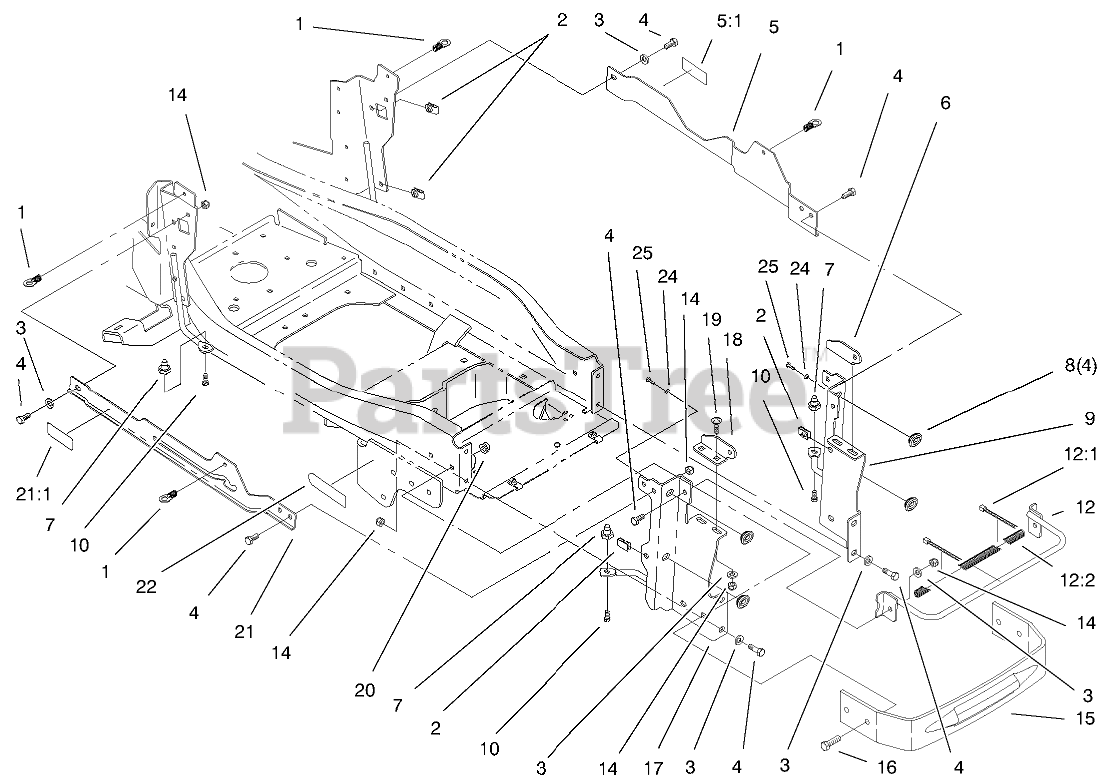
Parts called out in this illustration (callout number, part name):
1	LATCH ASM
3	WASHER-PLAIN
4	SCREW-HH
5	Support ASM (Only On: 73470, 73540)
5	Support ASM (Only On: 73541)
5:1	Decal-Warning (Only On: 73470, 73540)
5:1	Decal-Warning (Only On: 73541)
6	BRKT-LOWER HINGE LH (BLACK)
7	MOUNT-SIDEPANEL
8	GROMMET
9	SUPPORT-HOOD, LH
10	SCREW-PLASTITE
12	ASSEMBLY - HOOD SUPPORT
12:1	COVER-BRACE
12:2	TIE-CABLE
14	NUT-LOCK, NI
15	BUMPER-FRAME
16	SCREW-HH
17	SUPPORT-HOOD, RH
18	BRKT-LOWER HINGE RH
19	SCREW-CARR
20	NUT-LOCK, NI
21	Support ASM (Only On: 73470, 73540)
21	Support ASM (Only On: 73541)
21:1	Decal-Warning (Only On: 73470, 73540)
21:1	Decal-Warning (Only On: 73541)
22	DECAL-ATTACH A-MATIC
24	Washer-Flat (Only On: 73541)
25	Screw-HH TAP (Only On: 73541)
26	Clamp-Tube (Only On: 73551, 73550)
27	Decal-Hot Surface (Only On: 73551, 73550)
